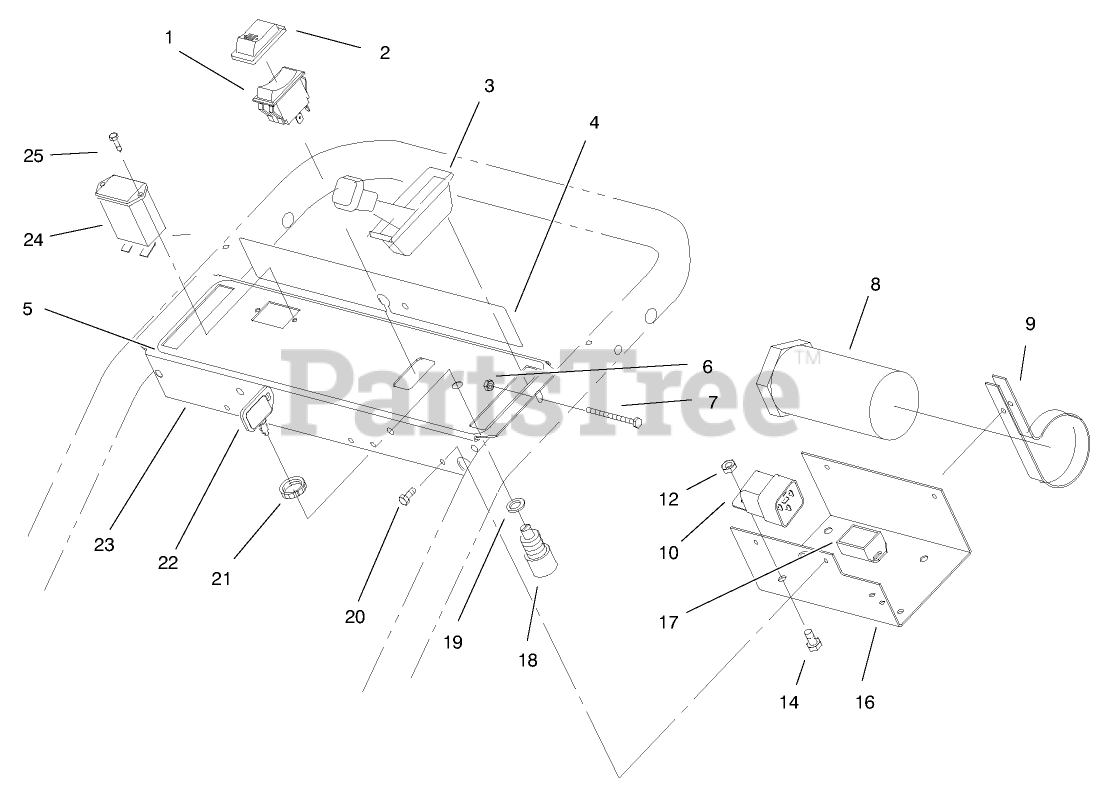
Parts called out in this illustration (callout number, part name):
1	SWITCH
2	BOOT-SWITCH
3	CONTROL-THROTTLE
4	DECAL-WARNING
5	DECAL - CONTROL PANEL
6	NUT-LOCK, NI
7	SCREW-SHH
8	TUBE-MANUAL
9	CLAMP-R
10	RELAY
12	NUT-LOCK, NI
14	SCREW-HH
16	PANEL-BOTTOM
17	MODULE
18	SWITCH-STARTER
19	WASHER-TOOTH, INTERNAL
20	SCREW-HWHTF
21	NUT-HH
22	KEY-IGNITION
23	PANEL - CONTROL
24	HOURMETER
25	SCREW-HWH
